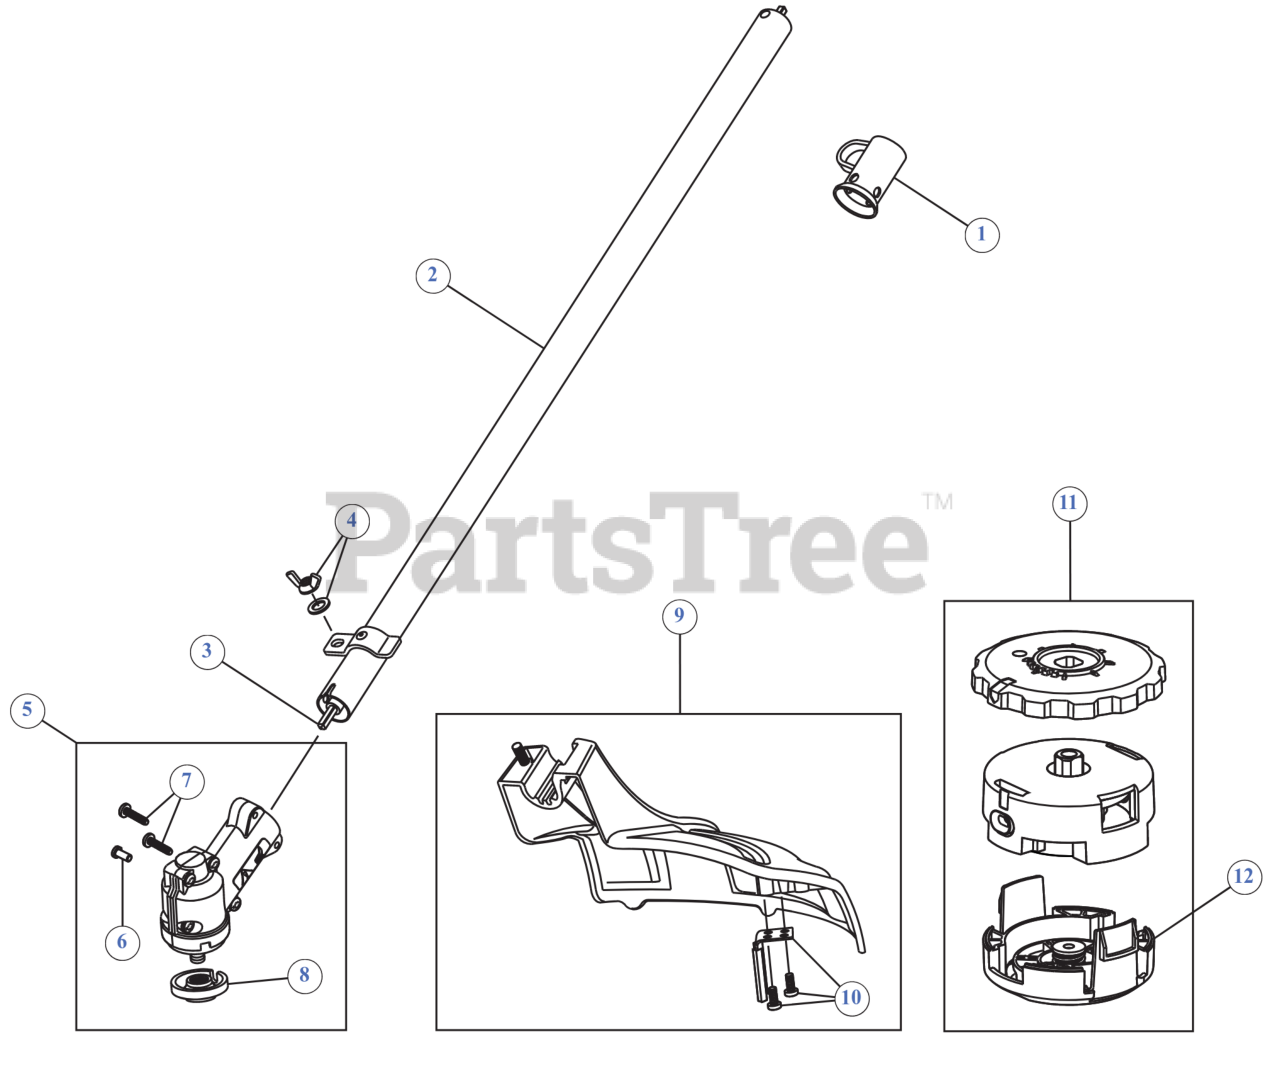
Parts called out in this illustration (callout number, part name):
1	HANGER
2	LOWER SHAFT HOUSING
3	LOWER DRIVE SHAFT
4	BLADE GUARD MOUNTING HARDWARE
5	GEARBOX LCBC
6	SCREW, 8-32 x .312 P
7	SCREW #10-24X11/16 T-25
8	CUTTING HEAD SPACER
9	GUARD/BLADE ASM
10	BLADE ASSEMBLY W/HDW
11	CUTTING HEAD
